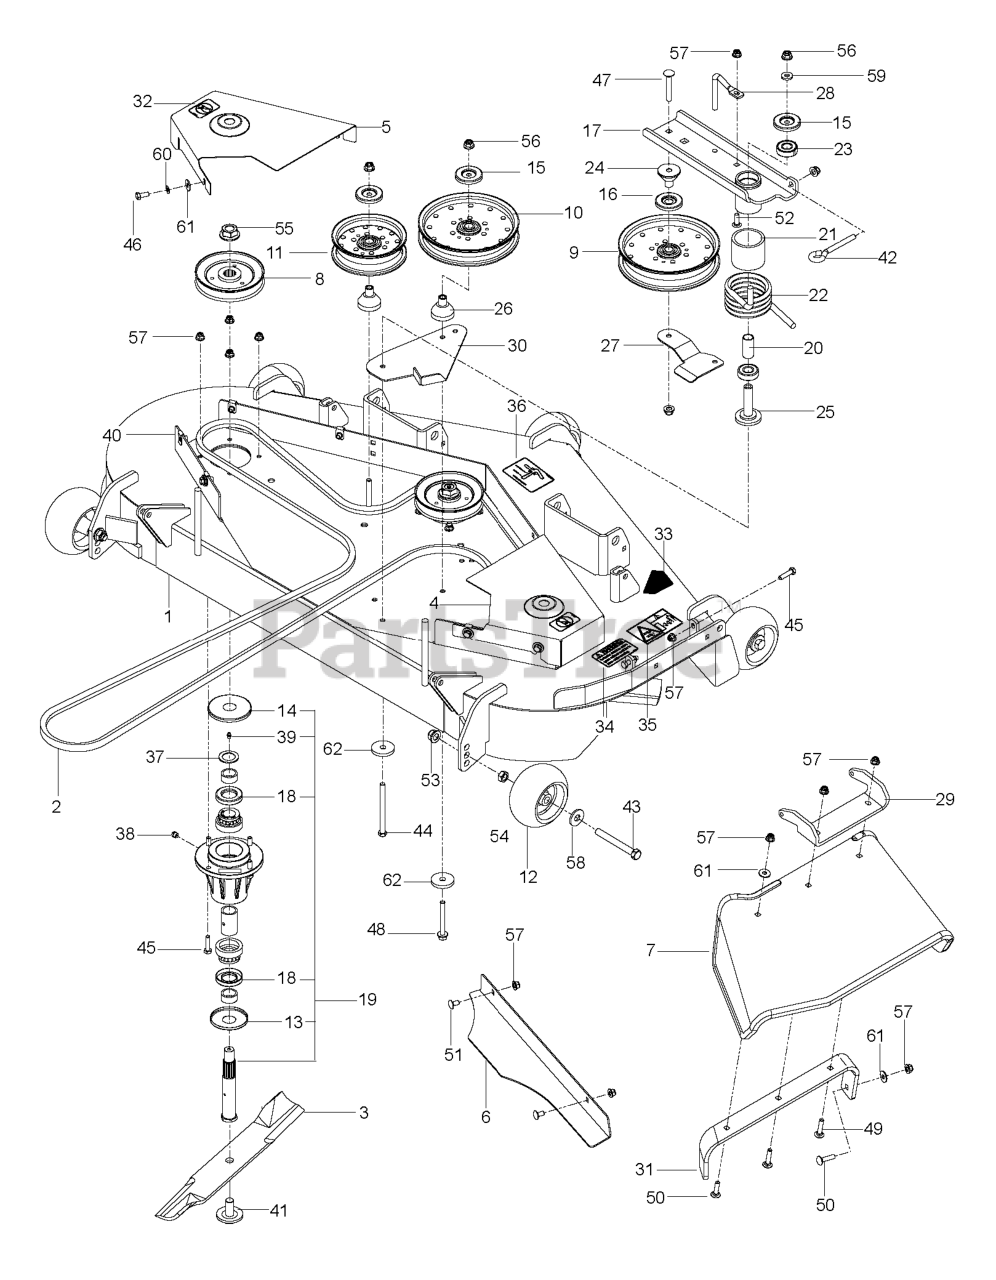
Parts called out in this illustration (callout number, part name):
1	DECK.SVC.W/DECALS.52.PZT.ORNGE
3	BLADE - HEAVY DUTY 18"
4	SHIELD BELT 52" RH ORANGE
5	SHIELD.BELT.52".LH.ORANGE
6	CONFINEMENT PLATE, 52"
7	CHUTE, RUBBER DISCHARGE 52/61"
8	PULLEY, 52
9	PULLEY - IDLER 7"
10	PULLEY - 7" NARROW
11	IDLER PULLEY
12	GAUGE WHEEL
13	BOTTOM DUST CAP
14	TOP DUST CAP
15	DUST SHIELD
16	SHIELD, DUST
17	IDLER.ARM.BLACK
18	SHAFT SEAL
19	HOUSING ASM, 52/61
20	SPACER, IDLER BEARINGS
21	SPACER, IDLER PIVOT
22	SPRING, TORSION, IDLER
23	BEARING, BALL
24	BEARING, IDLER ARM
25	BEARING, IDLER PIVOT
26	BEARING, IDLER STANDOFF
27	BELT.GUIDE.BLACK
28	BELT KEEPER
29	PIVOT BRACKET - CHUTE
30	BRACKET, SPRING STOP
31	BRKT, REINF - CHUTE 52/61"
32	DECAL, NO STEP
33	DECAL, CPSC
34	DECAL, CAUTION
35	DECAL, EURO SEVERING
36	DECAL, BELT ROUTING
37	MACHINE BUSHING
38	PLUG-VENTED
40	U-CLIP 5/16-18 NUT RETAINER
41	BLADE BOLT/WASHER
42	EYE BOLT, 3/8 X 4"
43	HCS 1/2-13 X 4 GR 5 ZD
44	HCS 3/8-16 X 4-1/2 GR 8 ZD
45	HCS 5/16C X 1 1/4
46	HCS 5/16C X 3/4
47	CARRIAGE BOLT 3/8-16 X
48	HHFS 3/8-16 X 3 GRD 5 ZD
49	RHSNB 5/16-18 X 1-1/2 GR 5 ZD
50	BOLT, CARRIAGE 5/16X1-1/4
51	CARRIAGE BOLT 5/16C X 5/8"
52	RHSSNB 5/16C X 1.0
53	NUT, 1/2-13 HEX FLG NYLOC ZD
54	NUT 1/2 HEX JAM
55	NUT FLANGE 3/4-16
56	NUT 3/8-16 HEX FLG NYLOC ZD
57	5/16-18 NYLOC FLANGE NUT
58	WASH USS FLAT 1/2
59	WASHER, 3/8 THICK
60	WASH 5/16 DISC SPRING ZD
61	WASHER 5/16 FLAT
62	SPINDLE WASHER
